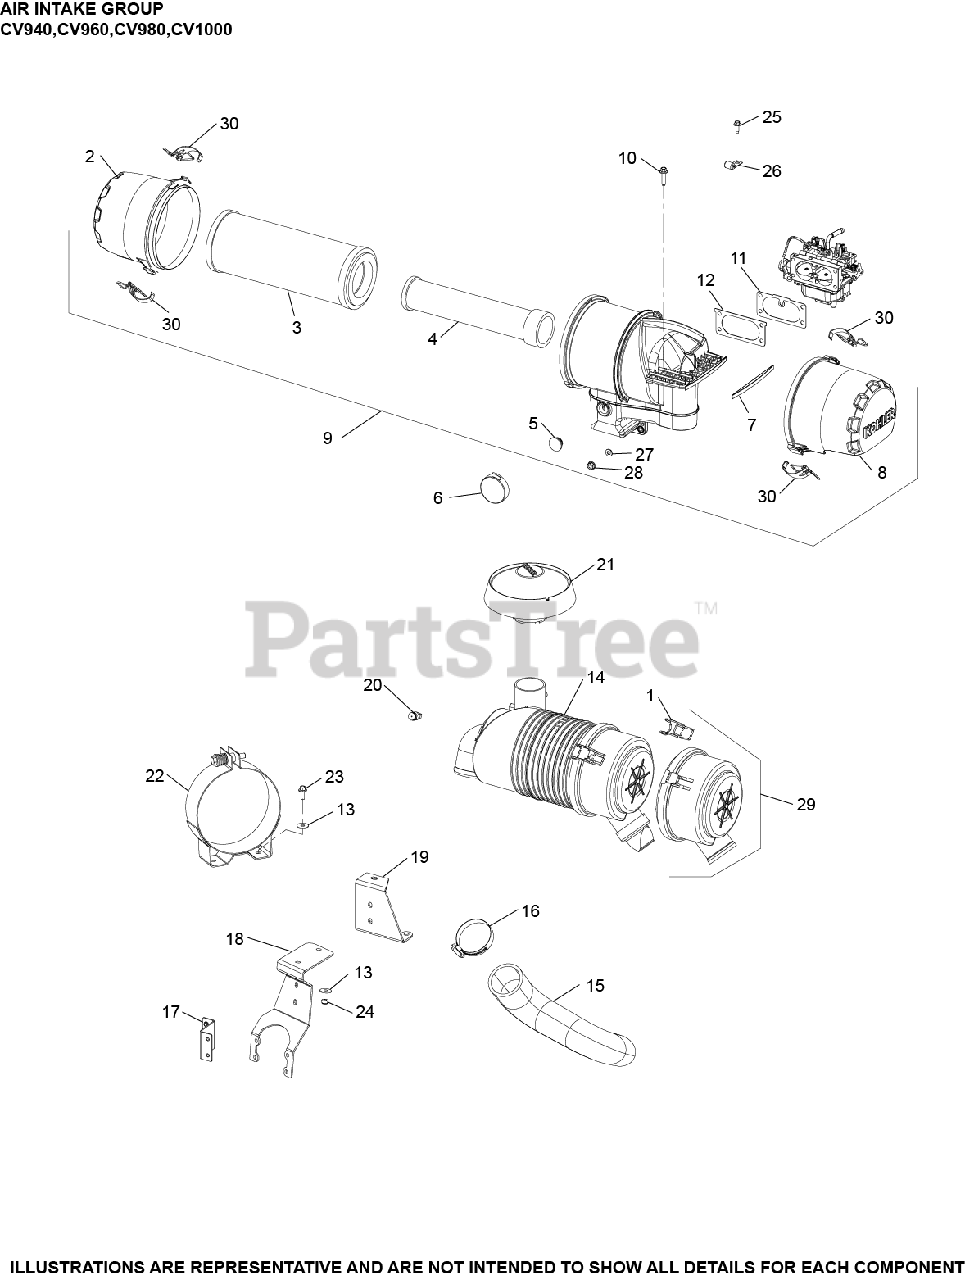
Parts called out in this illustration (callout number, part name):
3	ELEMENT, AIR FILTER - PRIMARY
4	ELEMENT, AIR FILTER - SAFETY
13	WASHER, FLAT 1/4"
15	HOSE, AIR CLEANER
16	CLAMP, HOSE
17	BRACKET, AIR CLEANER
18	BRACKET, LWR REMOTE A/C MOUNTI
19	BRACKET, UPPER REMOTE A/C MOUNTI
20	PLUG, PIPE
21	HOOD, INLET
22	BRACKET, AIR CLEANER
23	SCREW, THREAD FORMING
23	SCREW, FLG M6X1.0X16
24	NUT, LOCK M6X1.0
25	SCREW, THREAD FORMING
27	WASHER, FLAT 1/4" (O.D. 1/2")
30	CLIP ASSEMBLY
